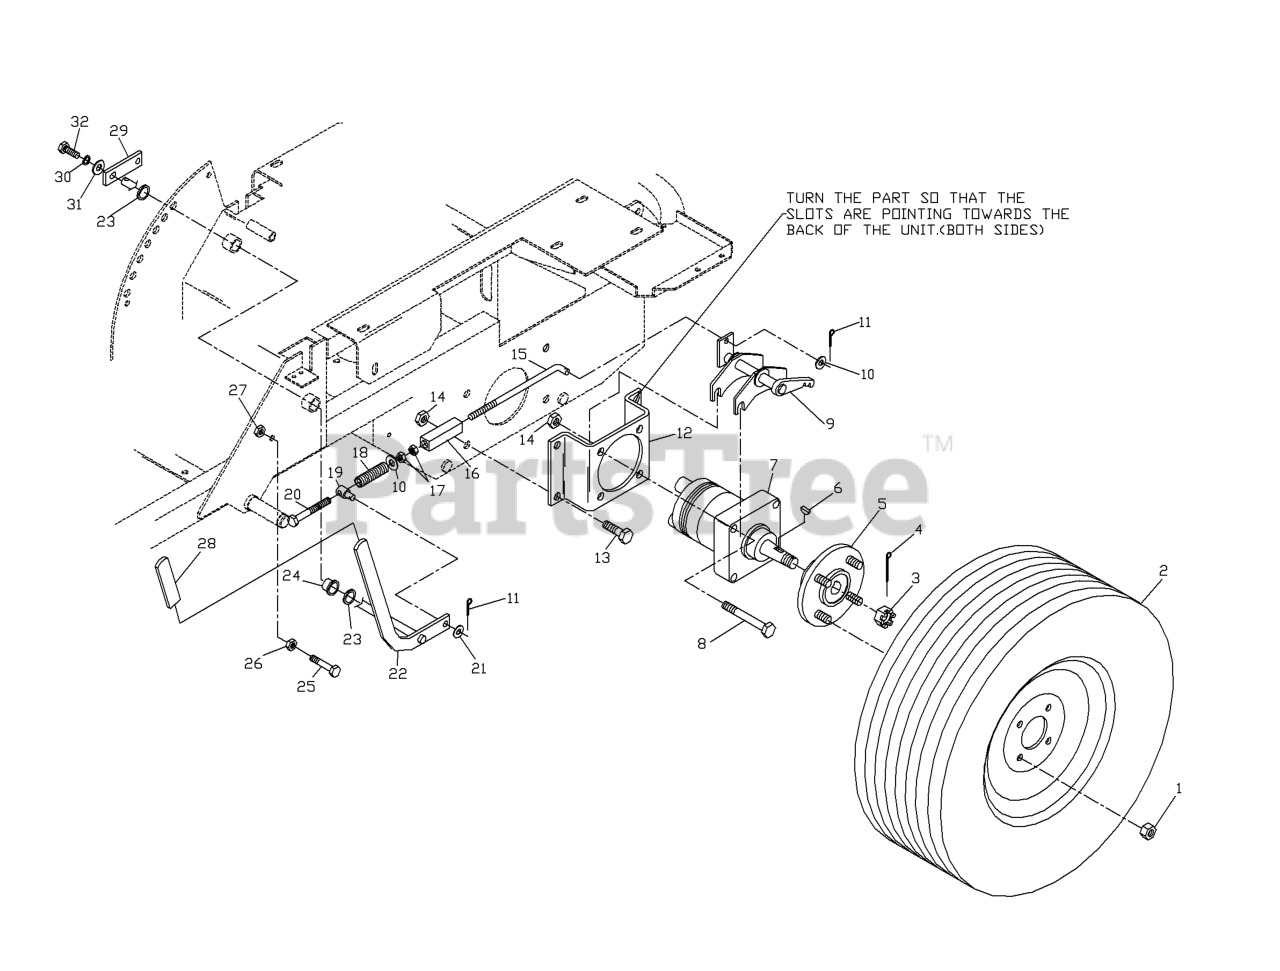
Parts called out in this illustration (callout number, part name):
1	LUG NUT 1/2F
2	TIRE & WHEEL ASM GRAY
2	TIRE 20X10-10
2	MODULAR RIM OFFSET
2	VALVE STEM TR-412
3	NUT 3/4-16 HEX SLTD GR5 ZD
4	COTTER PIN
5	HUB W/SPROCKET
6	KEY, #808 WOODRUFF
7	WHEEL MOTOR
8	HCS 1/2C X 2 3/4
9	BRAKE WELDMENT, LEFT
10	WASHER 5/16 FLAT
11	RP_COTTER PIN 1/8 X 3/4
12	MOTOR STANDOFF
13	HCS 1/2C X 1 1/4 SERRATED HEAD
14	NUT 1/2-13 HEX NYLOC ZD
15	BRAKE LINKAGE
16	TURNBUCKLE
17	NUT 5/16C HEX
19	BRAKE SWIVEL
20	HCS 5/16C, SPECIAL
21	WASHER 3/8 SAE FLAT
22	PIVOT SHAFT WELDMENT
23	WASHER, 7/16 DISC SPRING
25	HCS 3/8-16 X 1 3/4 GR5
26	NUT 3/8C WHIZ
27	NUT 3/8C CENTERBLOCK
29	ARM, PARK BRAKE
30	LOCKWASHER 1/4"
31	WASHER 1/4 FLAT
32	HCS 1/4C X 5/8
